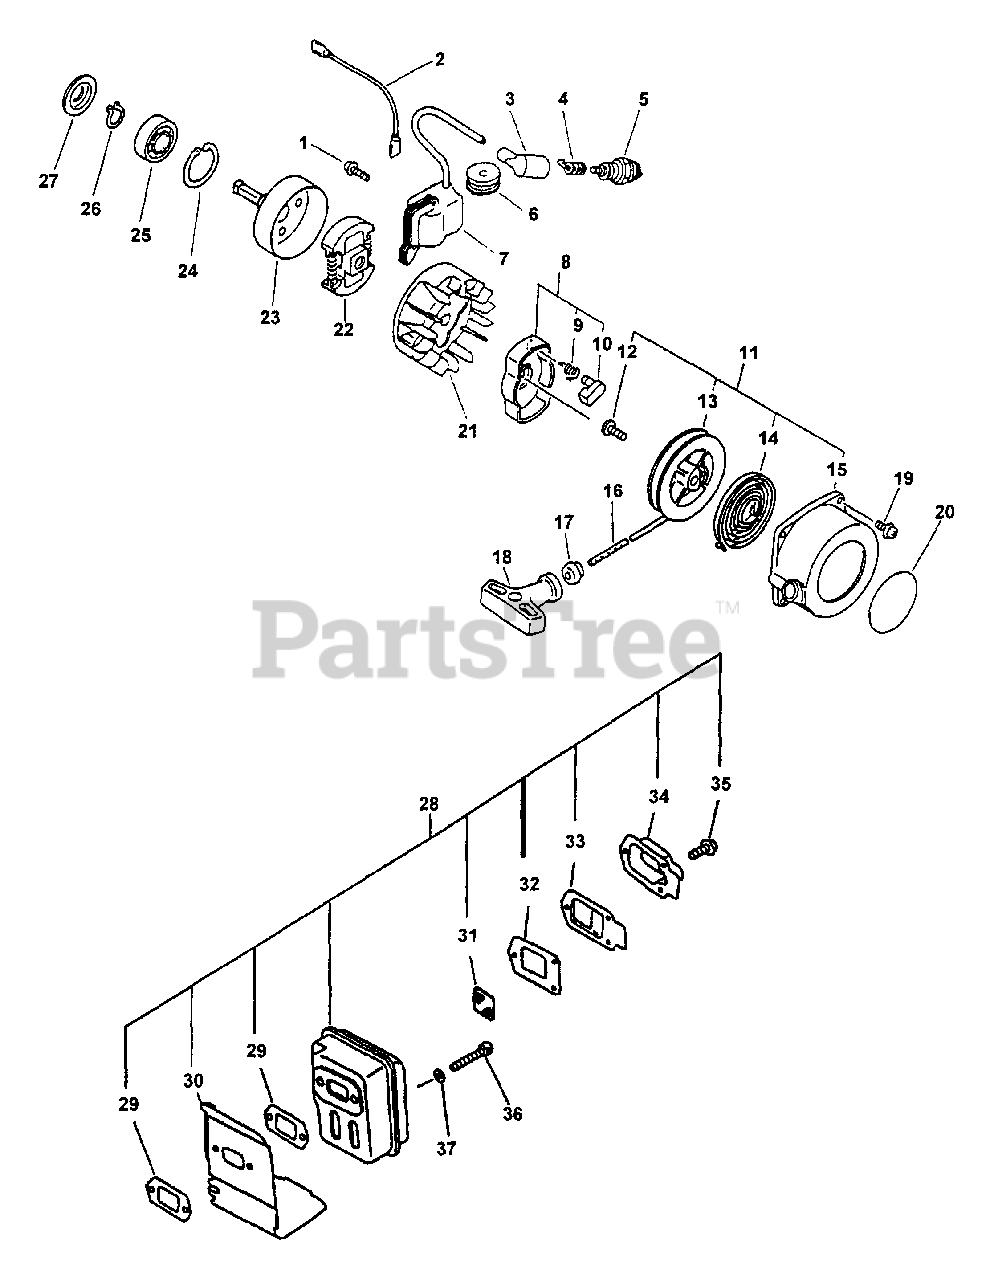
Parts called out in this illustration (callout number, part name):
1	SCREW 4×22
2	LEAD - GROUND
3	CAP, SPARK PLUG
4	TERMINAL, SPARK PLUG
5	SPARK PLUG - BPM-7Y
7	COIL, IGNITION
8	PAWL ASSY, STARTER
9	SPRING, RETURN
10	PAWL, STARTER - BLACK
11	STARTER ASSY, RECOIL
12	SCREW
13	REEL, ROPE
14	SPRING, RECOIL
15	CASE, RECOIL STARTER
17	GUIDE, ROPE
18	GRIP, STARTER
19	BOLT 4×16
20	LABEL, BRAND
22	CLUTCH ASSY
23	DRUM, CLUTCH
24	RING, SNAP Ø32
25	BEARING, BALL 6201-ZZ
26	RING, RETAINING - 12
27	STOPPER, PIPE
28	MUFFLER ASSY
29	GASKET, EXHAUST
30	COVER, EXHAUST
31	SCREEN, SPARK ARRESTER
32	GASKET, EXHAUST
33	GUIDE, EXHAUST
34	GUIDE, EXHAUST
34	OUTLET, EXHAUST
35	SCREW 4×10
36	BOLT 5×55
37	WASHER, FLAT 5.5×10×0.8
